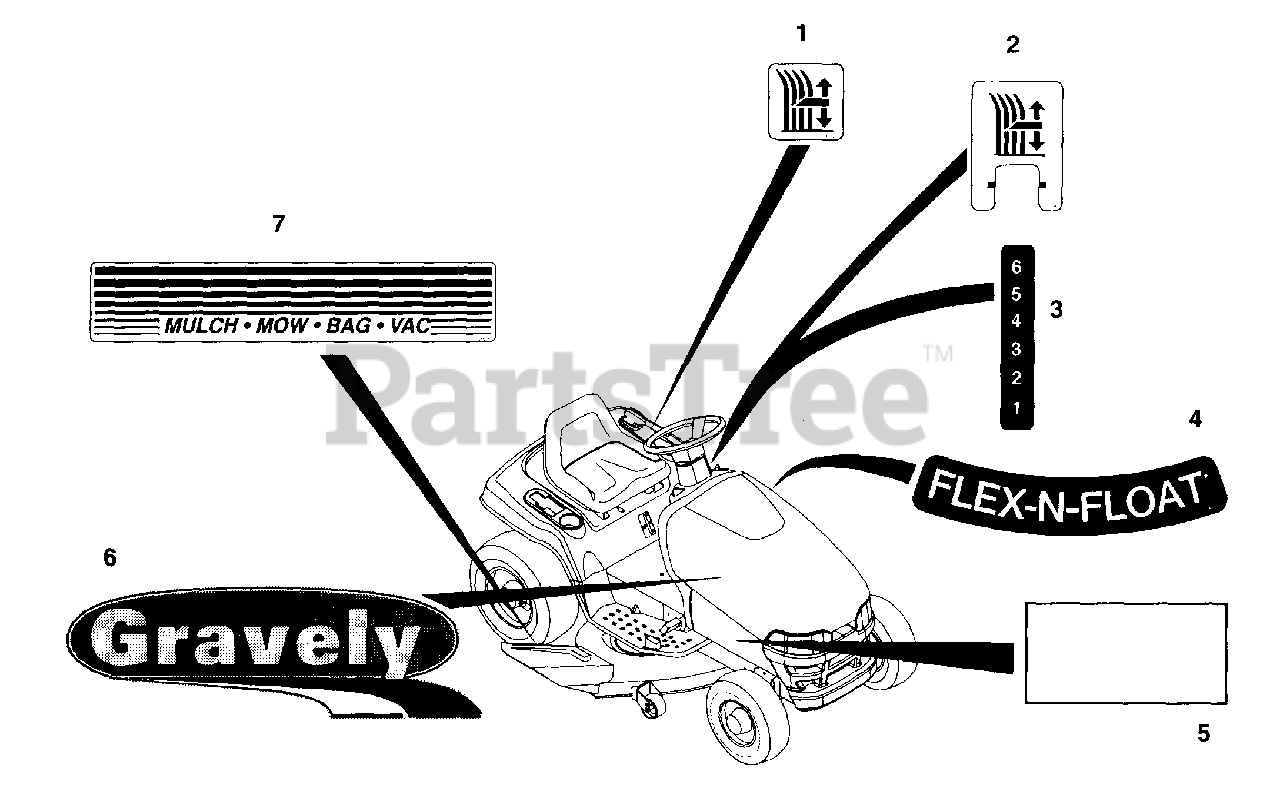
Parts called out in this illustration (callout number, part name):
1	Decal-Cut Height-Insert
2	Decal-Cut Height-Frame
3	Decal-Indicator 6 Pos
4	Decal-Flex-N-Float
5	Decal-GLT 548
6	Decal-Gravely Logo Left Hand 17"
6	Decal-Gravely Logo Right Hand 17"
7	Decal-Mulch-Mow-Bag-Vac
